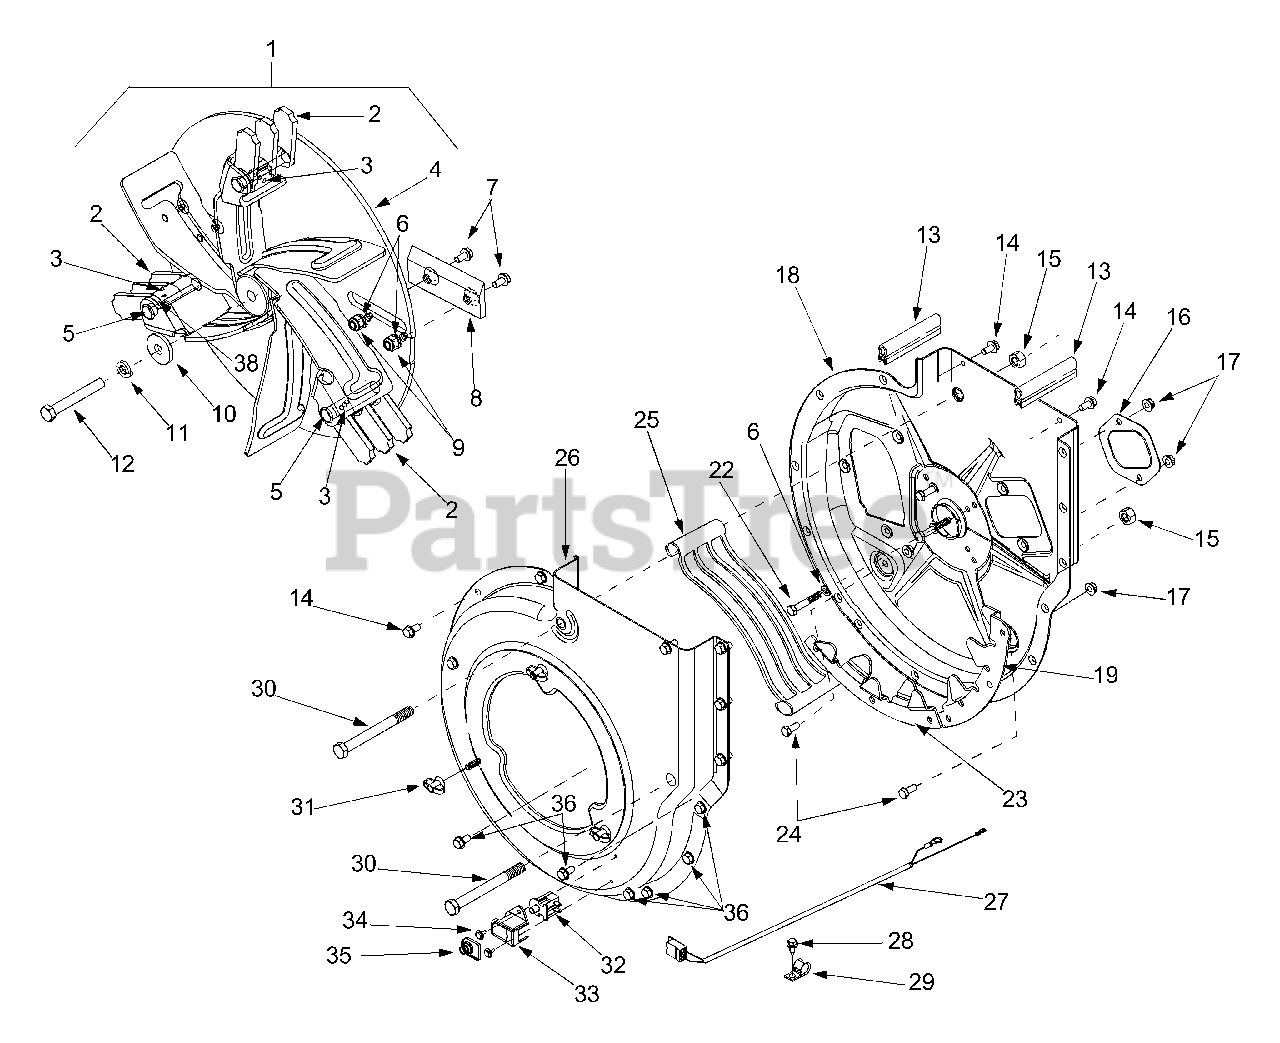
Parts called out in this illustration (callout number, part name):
1	Impeller Assembly Complete
2	Flail Blade
3	Spiral Pin
4	Impeller Assembly
5	Clevis Pin
6	Lock Washer 5/16
7	Cap Screw 5/16-24 x 1.0
8	Chipper Blade
9	Hex Lock Nut 5/16-24
10	Flat Washer.406 x 1/1/4
11	Lock Washer 3/8
12	Hex Cap Screw 3/8-24 x 2.75
13	Rubber Seal
14	Hex Washer Screw 5/16-18
15	Hex Lock Nut 1/2-13
17	Hex Flange Lock Nut 5/16-18
22	Hex Cap Screw 5/16-18 x 2
24	Hex Cap Screw 5/16-18 x.75
25	Discharge Screen
27	Wire Harness
28	Hex Washer Screw 1/4-14 x.625
29	Clamp
30	Hex Cap Screw 1/2-13 x 5.0
31	Knob 5/16-18
32	Switch
33	Safety Switch Mounting Cover
34	Hex Washer Screw
35	Switch Cover
36	Screw 5/16-18 x.750
38	Retaining Pin Clip
